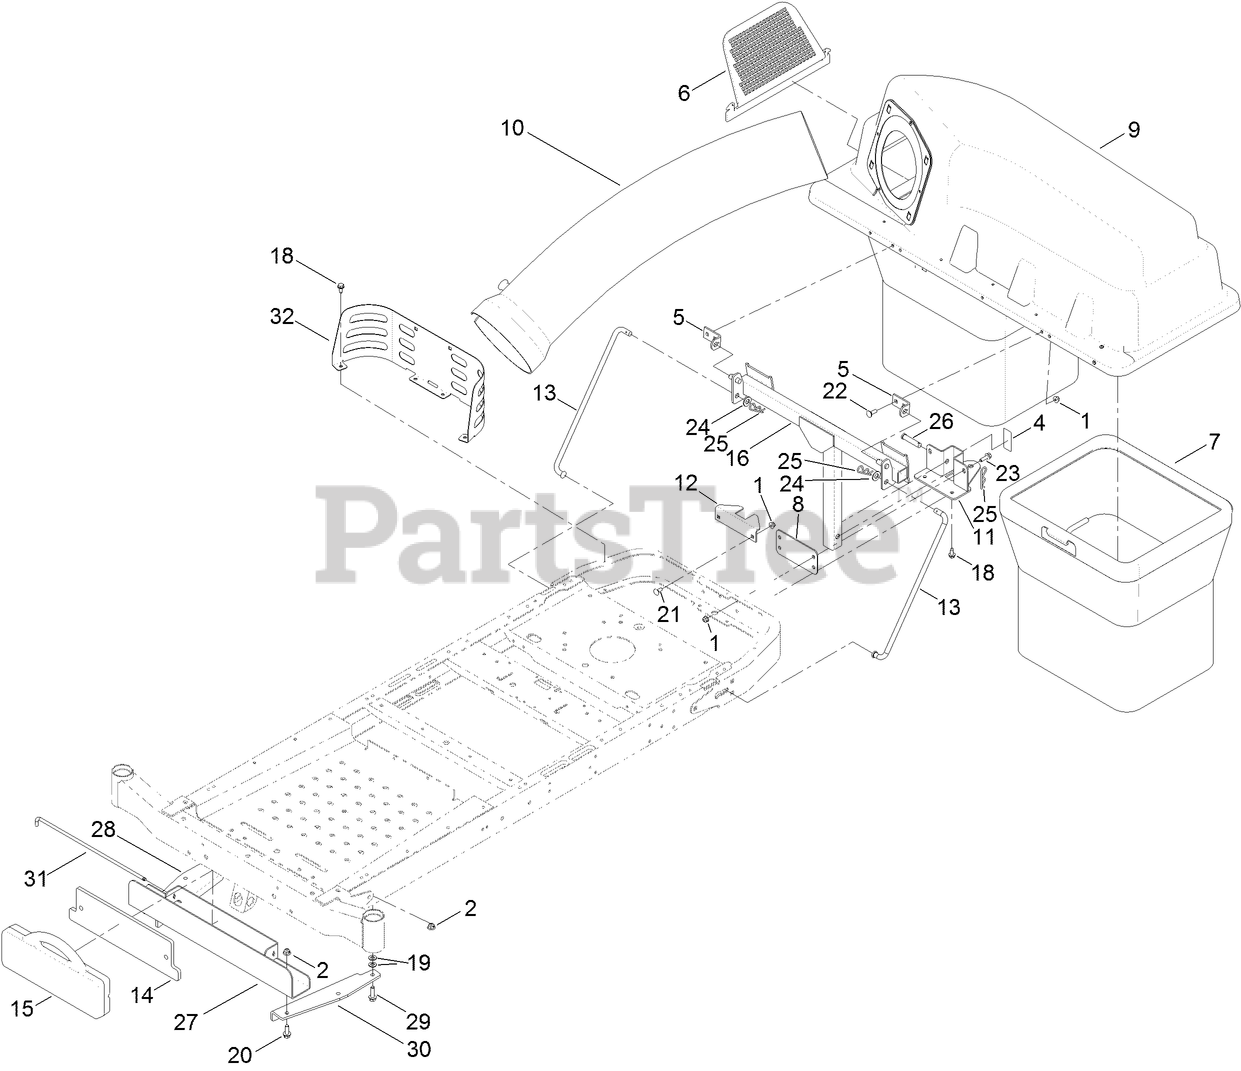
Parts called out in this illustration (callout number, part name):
1	NUT-HF, NI
2	NUT-HF, NI
5	BRACKET-PIVOT, HOPPER
6	SCREEN-BAGGER
7	BAG ASM
9	BAGGER TOP ASM
10	TUBE-BAGGER
11	SUPPORT-BAGGER
12	BRACKET-STABILIZER
13	ROD-SUPPORT
16	FRAME-PIVOT
18	SCREW-HWHTF
19	WASHER-FLAT
20	SCREW-HHF
21	BOLT-CARR
22	BOLT-CARR
23	SCREW-HHF
24	WASHER-FLAT
25	PIN-HAIR
26	PIN-CLEVIS
27	CHANNEL-WEIGHT, BAGGER
28	BRACKET-BAGGER WEIGHT, RH
29	SCREW-HHF
30	BRACKET-BAGGER WEIGHT, LH
31	PIN-WEIGHT
32	GUARD-REAR
